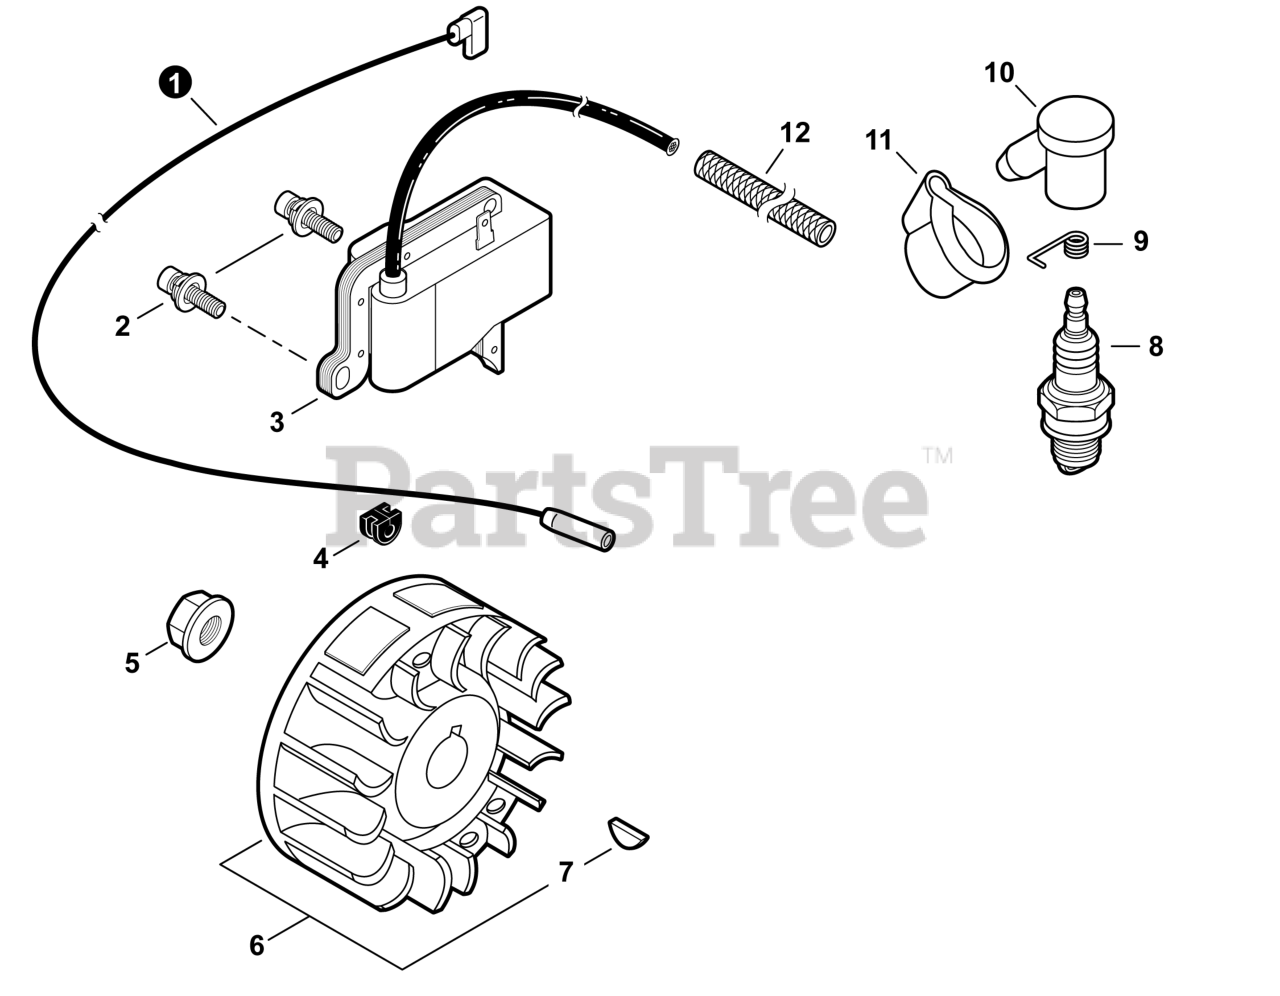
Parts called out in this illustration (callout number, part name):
1	LEAD 170 MM
2	BOLT 5x20
3	COIL, IGNITION
5	NUT, FLANGE 10x1.25
6	FLYWHEEL KIT
7	KEY, WOODRUFF 3x14
8	SPARK PLUG - BPMR7A
9	TERMINAL, SPARK PLUG
10	CAP, SPARK PLUG
11	COVER, DUST
12	TUBE, INSULATOR 7x8.6x55
